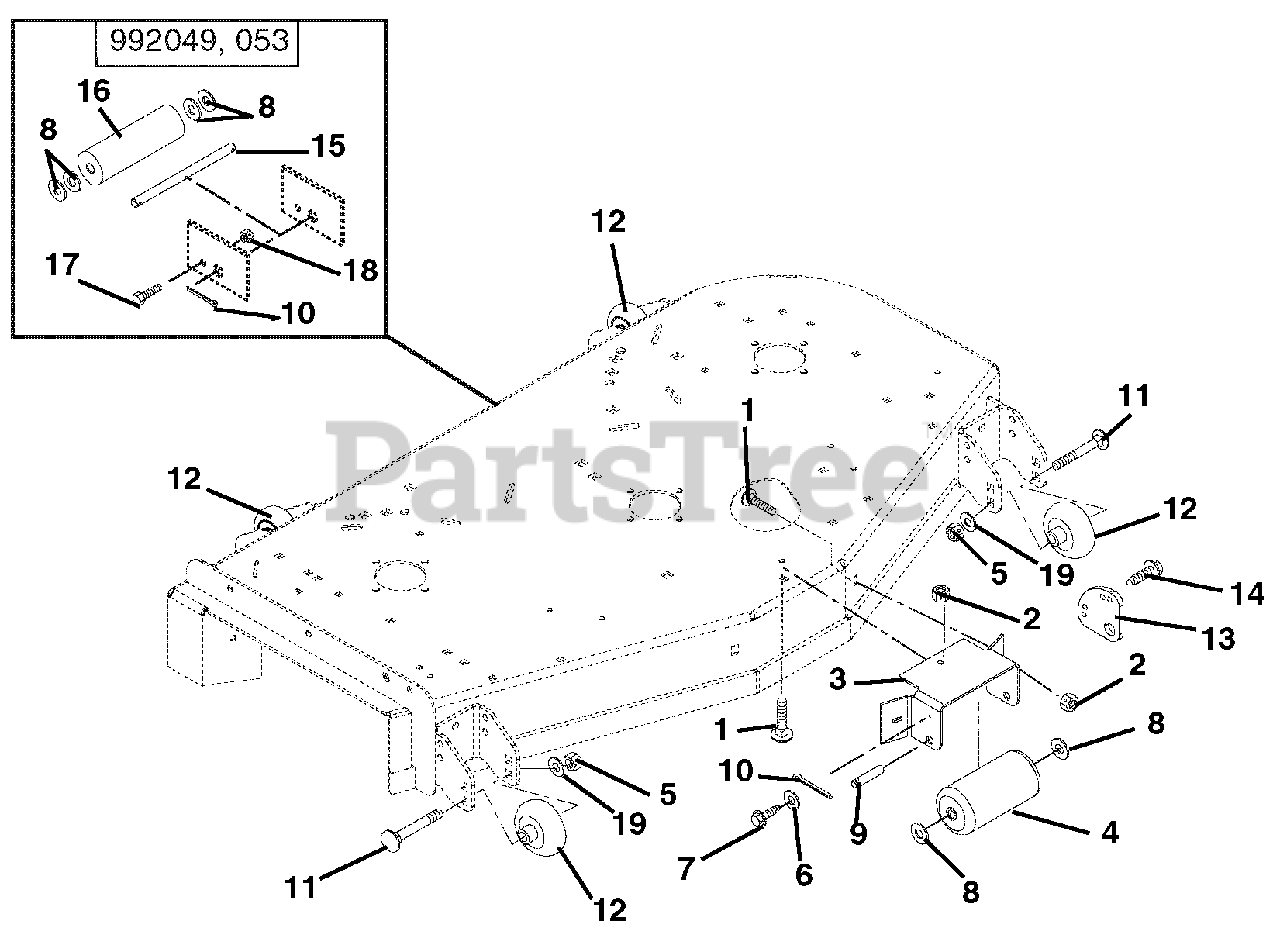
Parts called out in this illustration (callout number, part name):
1	Bolt-Round Head Square Neck .38-16 x 1.00 Grade 5
2	Nut-Locking-Top-Flange .38-16
3	Bracket- Anti-Scalp Roller (046, 047, 048, 049, 053)
5	Nut-Locking-Nylon .50-13
6	Washer-Flat-Steel .281 x .62 x .065
7	Screw-Tapping .25-20 x .75 Hex Washer Head
8	Washer-Flat-Steel .656 x 1.31 x .095 (045, 046 , 047, 048, 052)
10	Pin-Cotter .25 x 2.00 (045, 046 , 047, 048, 053)
11	Bolt-Round Head Square Neck .50-13 x 5.00 Grade 2
12	Wheel, 3 x 5
13	Anti-Scalp Washer
14	Screw-Tapping .25-20 x .62 Hex Washer Head
15	Shift, Center Roller (049, 053)
16	Roller, Gage (049, 053)
17	Bolt-Hex .25-20 x .75 Grade 5 (049, 053)
18	Nut-Locking-Center .25-20 (049, 053)
19	Washer-Flat-Steel .531 x 1.06 x .095
